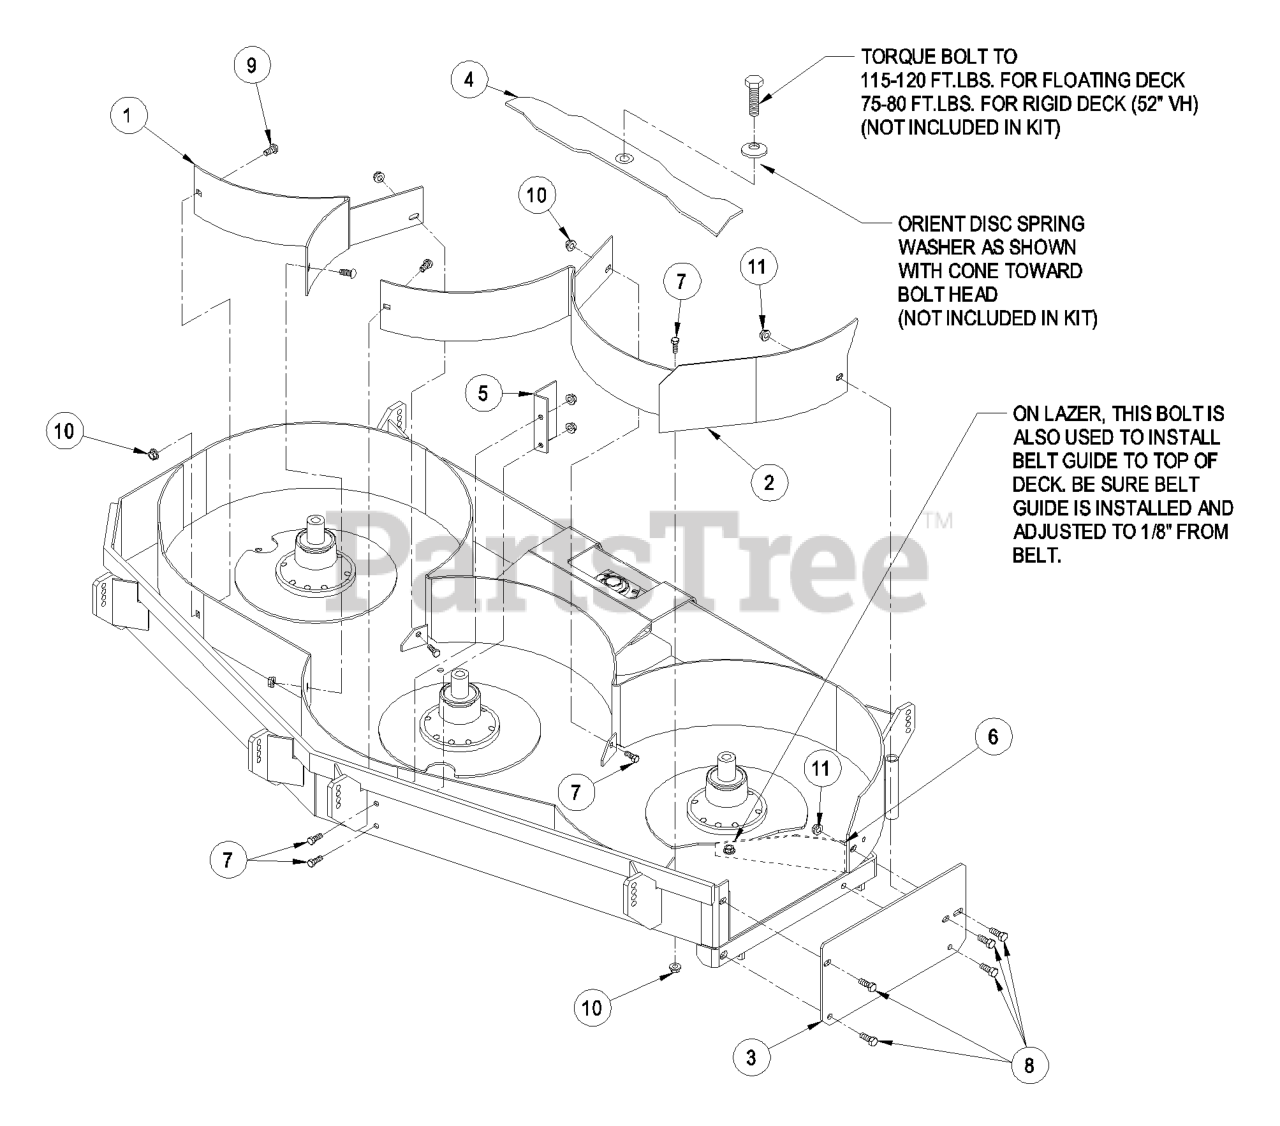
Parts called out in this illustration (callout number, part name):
1	WLD,BAFFLE MULCH LH 52
2	WLD,BAFFLE MULCH RH 52
3	COVER-MULCH PLATE
5	BAFFLE,ZEE MULCH 52
6	WLD,BAFFLE DISCHARGE
7	SCREW-HH
8	SCREW-HH
9	BOLT-CARR
11	NUT-HHF, WHIZ
